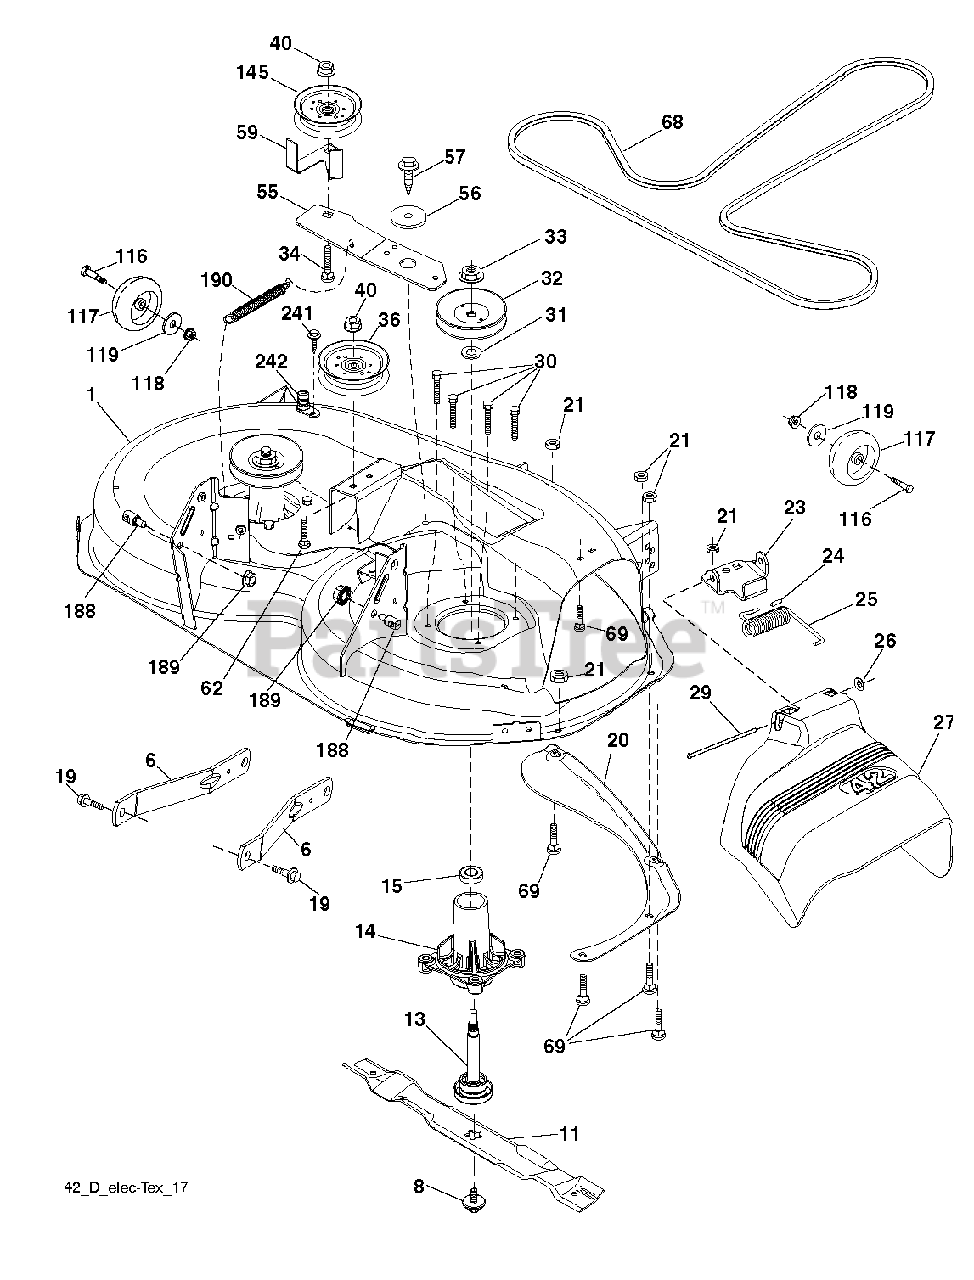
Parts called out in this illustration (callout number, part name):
1	DECK.WELDMENT.42"
6	ARM.SUSPENSION.MOWER.R
8	BOLT.WASHER.ASM.7/16-2
11	42" HI-LIFT BLADE
13	SHAFT.ASM.MDRL.N/GREASE.38
14	HOUSING MANDREL
19	BOLT.SHOULDER
20	BAFFLE.VORTEX
21	LOCKNUT
23	BRKT.DEFLECTOR.38"2005+
24	CAP-SLEEVE LT
25	SPRING.TORSION.DEFLECT
26	NUT PUSH M
27	SHIELD.DEFLECTOR.MOWER.42"BLAC
29	ROD.HINGE
30	SCREW, WASHER HEAD
31	WASHER.SPACER.MANDREL
32	PULLEY/MANDREL
33	NUT.FLANGE.LOCK.TOP
34	BOLT.3/8-16X1.50
36	PULLEY.IDLER.2006
40	NUT LOCK FLG 3/8-16 UNC
55	IDLER.ARM
56	SPACER.RETAINER
57	SCREW 3/8-16X1
59	GUARD, BELT
62	BOLT
68	BELT V SECONDARY
69	BOLT
117	WHEEL.GAGE.HALF.SPOKED
118	NUT LOCK FLG 3/8-16 UNC
119	WASHER
145	PULLEY.IDLER.48"PRIMARY
188	STUD.FASTNER.W/ANTI-ROTATE
189	NUT LOCK HEX FLANGE 5/16-18
190	SPRING.MOWER.DRIVE.ELECTRIC
242	PORT.WASHOUT
